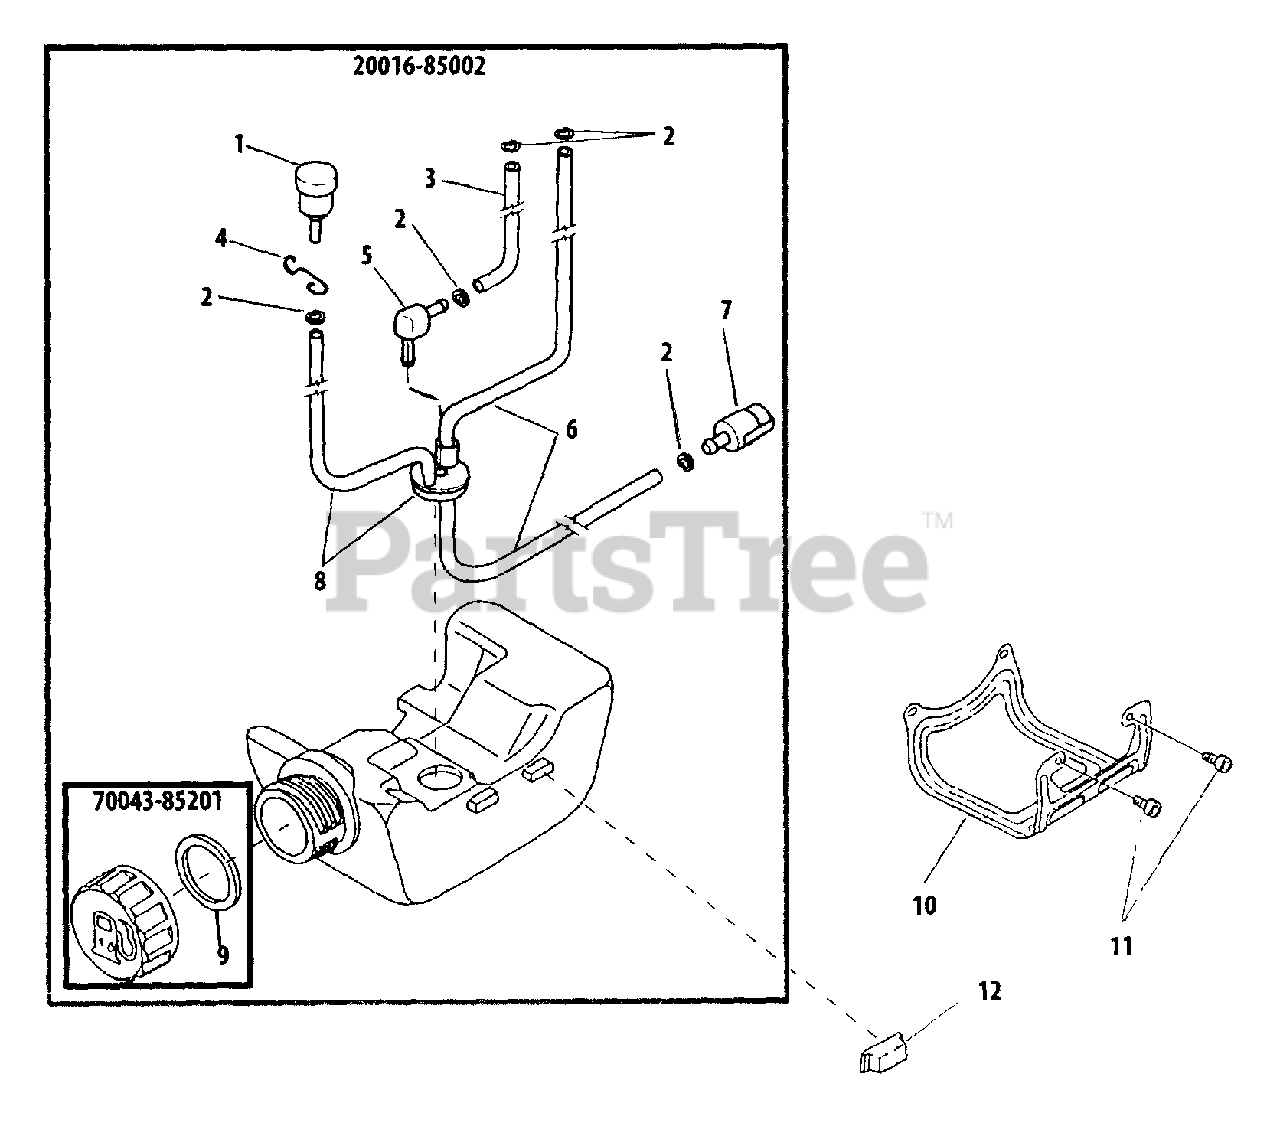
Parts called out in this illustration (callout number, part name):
1	VENT, FUEL TANK
2	RING, RETAINING - 6
3	PIPE - RETURN
4	HOLDER, VENT
5	CONNECTOR, PIPE
6	PIPE - FUEL
7	FILTER, FUEL
8	GROMMET
9	GASKET, CAP
10	GUARD, FUEL TANK
11	SCREW - 5X12
12	CUSHION, TANK
20016-85002	FUEL TANK ASSY
70043-85201	CAP ASSY
